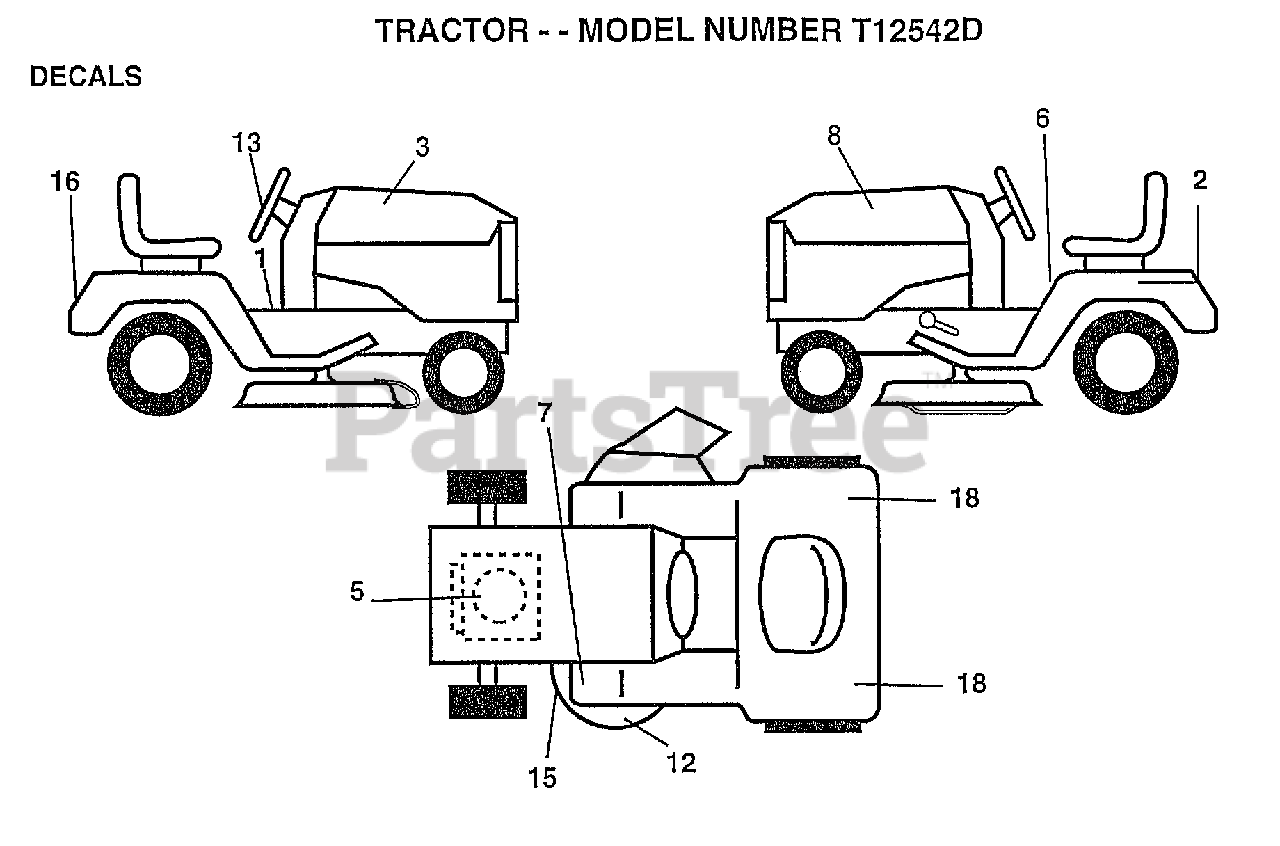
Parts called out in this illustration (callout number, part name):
2	DECAL.BTRY.DANGER
3	DECAL.HD.RH.12.5
5	DECAL, HP ENGINE
6	DECAL
8	DECAL.HD.LH.12.5
13	"DECAL,STR WHL T"
15	DECAL
16	DECAL.FENDER
18	REFLECTOR-TAIL YT
